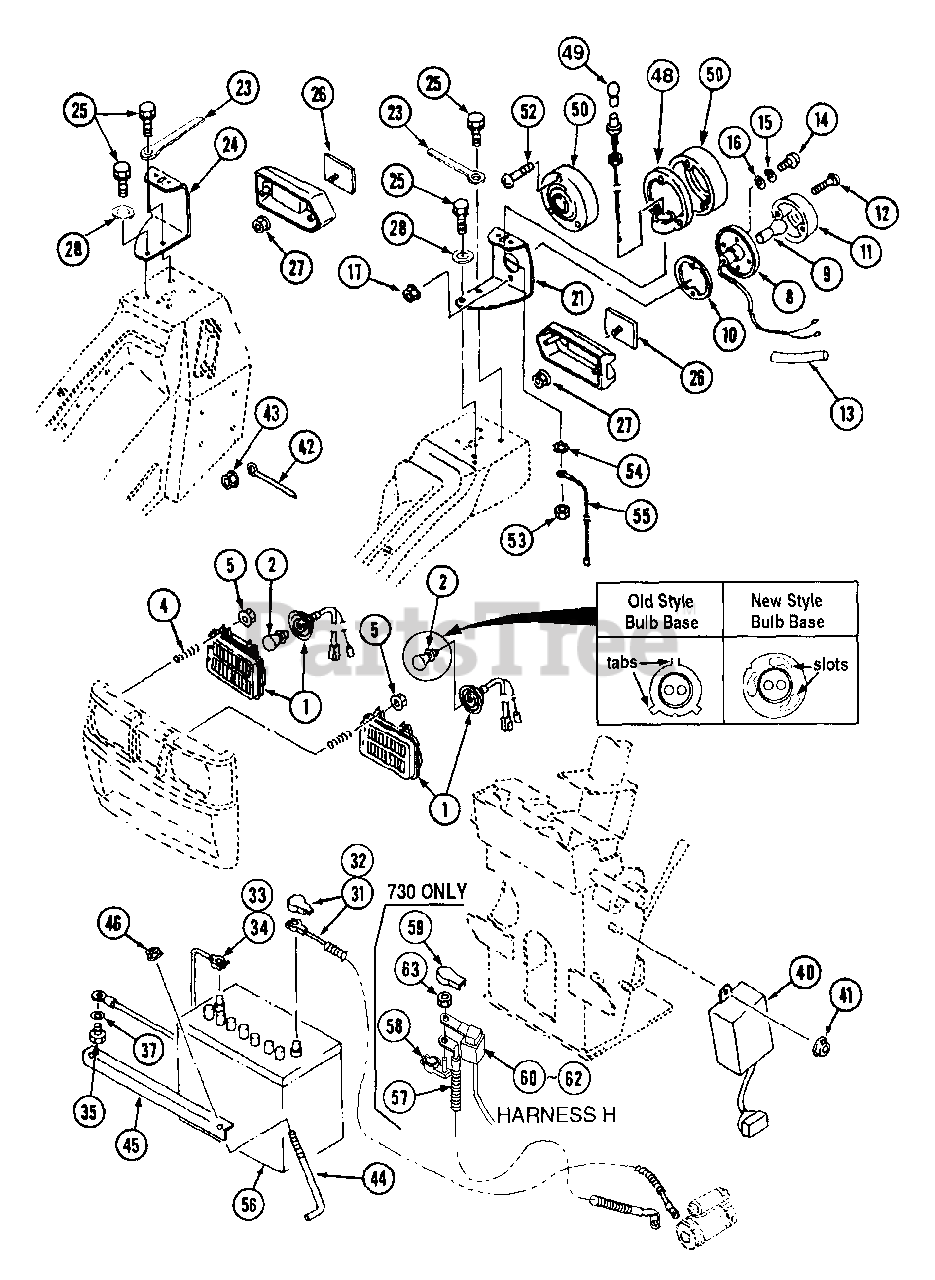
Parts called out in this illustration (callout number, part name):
1	Lamp, Head
8	Socket
15	Washer, Spring
21	Bracket, Lamp L.H.
24	Bracket, Lamp R.H.
31	Cord Ass'y.
32	Cord Ass'y.
33	Cord, Battery
34	Cord, Battery
45	Clamp, Battery
48	Body
49	Bulb
54	Washer, Tooth
56	Battery, 500CCA
60	Fuse Box
